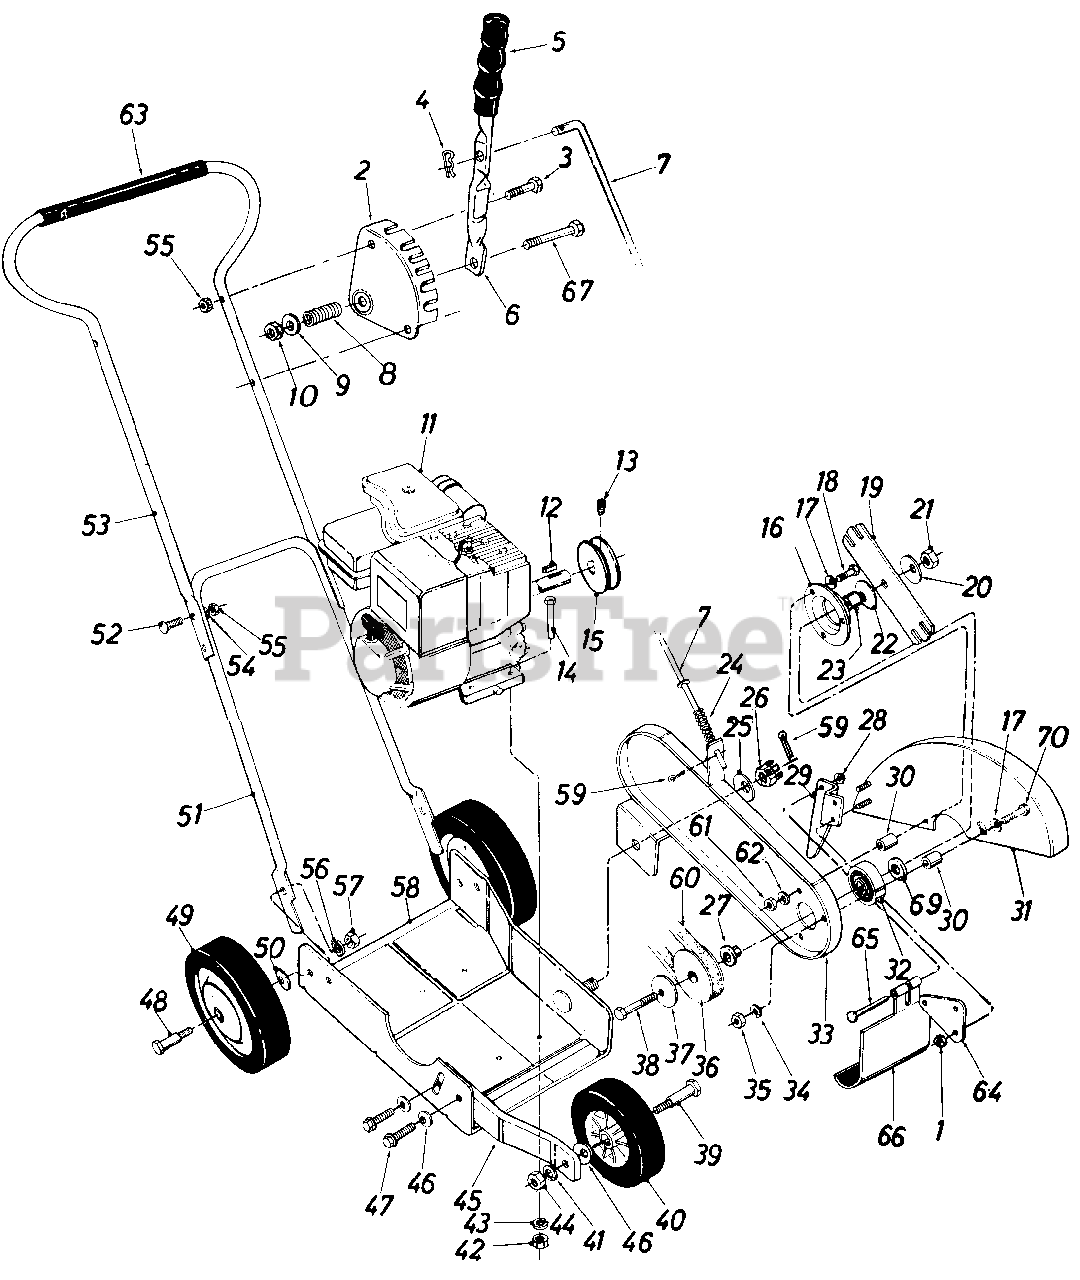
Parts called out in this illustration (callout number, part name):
1	Hex Cent. L.-Nut 1/4-20 Thd.
3	Hex Bolt 1/4-20 x 1.25" Lg.*
4	Cotter Pin 1/8" Dia. x 1.0" Lg. *
5	Grip
7	Clutch Rod
8	Compression Spring .50" O.D. x 1.38" Lg.
9	Fl.-Wash. .34" 1 D. x .62" O.D x.063
10	Hex Cent. L.-Nut 5/16-18 Thd.
11	Engine
12	Sq.Key 3/16 x 1.0" Lg.*
13	Set Scr. 1/4-28 x 1/4" Lg.
14	Hex Bolt 5/16-18 x 1.50" Lg.*
15	Engine Pulley
16	Bearing Housing
17	Bell.-Wash. .34" I.D. x 88" O.D. x .060
18	Hex Bolt 5/16-18 x 1.25" Lg.*
20	Bell.-Wash. .535" I.D. x 1.50" O.D. x.052
21	Hex Cent. L.-Nut 1/2-20 Thd.
22	Bell.-Wash. .535" I.D. x 1.50" O.D. x.052
23	Spacer
24	Compression Spring .57" O.D. x 1.92" Lg.
25	Bell.-Wash. .535" I.D. x 1.50" O.D. x .052
26	Hex Castle Nut 1/2-2 Thd.
27	Shoulder Spacer
28	Push Cap
29	Guide
30	Spacer.354" I.D. x.635"O.D. x .510" Lg.
33	Spindle Bracket Ass'y.
34	L.-Wash. 5/16" I.D.*
35	Hex Nut 5/16-18 Thd.
36	Pulley
37	Bell.-Wash. .535" I.D. x 1.50" O.D. x.052
38	Hex Bolt 1/2-20 x 3.50" Lg.*
39	Shoulder Bolt .498" Dia. x 1 .450
40	Wheel Ass'y. Comp. 6" Dia. x 1.50
41	L.-Wash. 3/8" I.D.*
42	Hex Nut 5/16-18 Thd. *
43	L.-Wash. 5/16" 1.D.*
44	Hex Nut 3/8-16 Thd.
45	Front Wheel Support
46	Bell.-Wash. .400" I.D. x 88" O.D. x.060
47	Hex Wash. Hd. Self Tap Scr. 3/8-16 x .75" Lg.
48	Shoulder Bolt.498" Dia. x 1 .450
49	Wheel Ass'y. Comp. 7" Dia. x 1.50
50	Bell.-Wash. .400" I.D. x 88"O.D.
51	Lower Handle
52	Carriage Bolt 1 /4-20 x 1 .25"
53	Upper Handle
54	L.-Wash. 1/4" I.D. *
55	Hex Nut 1/4-20 Thd.*
56	L.-Wash. 3/8" I.D.*
57	Hex Nut 3/8-16 Thd.*
58	Base Ass'y.
59	Cotter Pin 1/8" Dia. x 1.0"
60	3V-Belt 31.2" Lg.
61	Hex Nut 5/16-18 Thd.
62	L.-Wash.5/16" I.D.*
63	Grip
64	Flap Bracket
65	Hinge Pin
66	Debris Deflector
67	Hex Bolt 5/16-18 x 1.75" Lg. *
69	Fl.-Wash. .51 I.D. x 1.00 O.D. x .060
70	Hex Bolt 5/16-18 x 2.00" Lg. *
